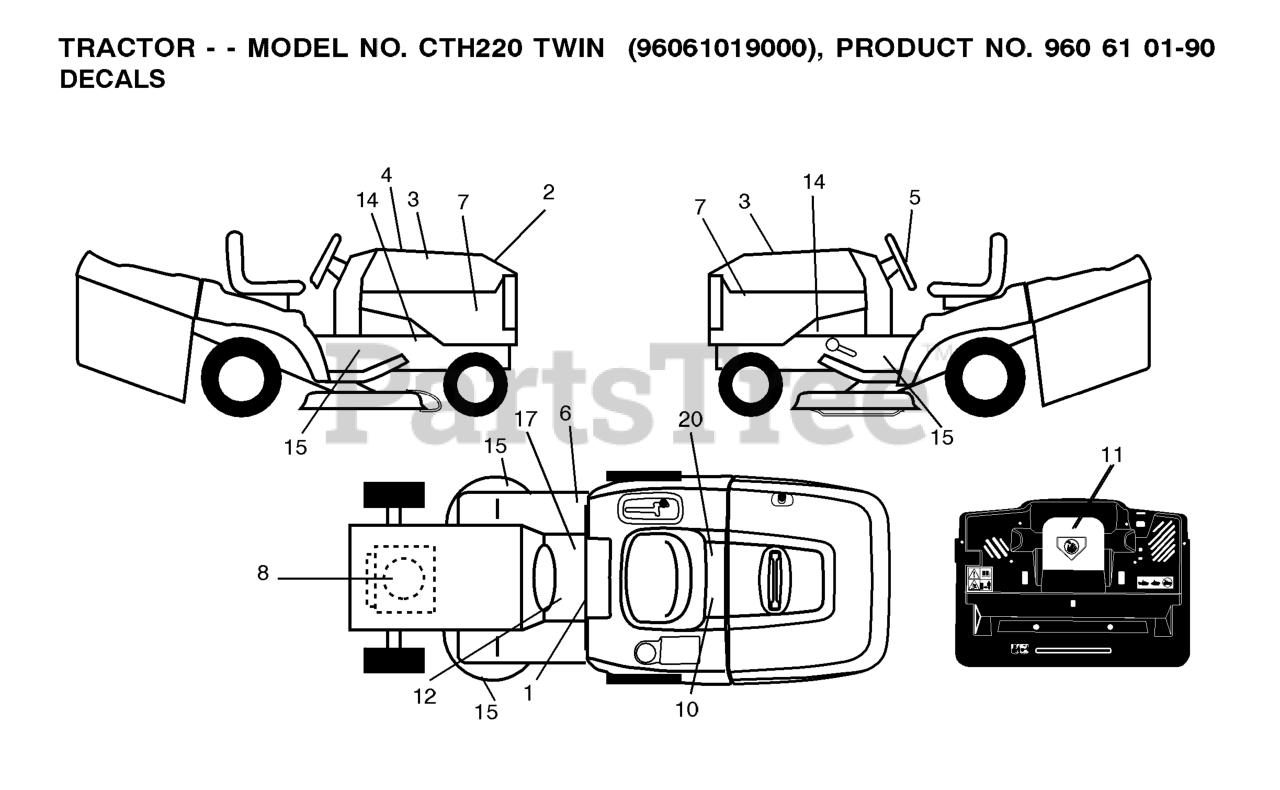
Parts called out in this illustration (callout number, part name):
1	LABEL
2	DECAL.HOOD.TOP.INSERT.
3	DECAL.HOOD.NAMELOGO.HUSQ
5	DECAL.WHEEL.STRG.LGN.H
6	Decal, Fender 100 DB/CE
8	DECAL
10	DECAL BTRY SYMBOLS
11	DECAL.INTERNATIONL.CUTFINGER
12	DECAL
17	DECAL PARK BRAKE
20	DECAL.BYPASS.FENDER.CRD.LT.YT
